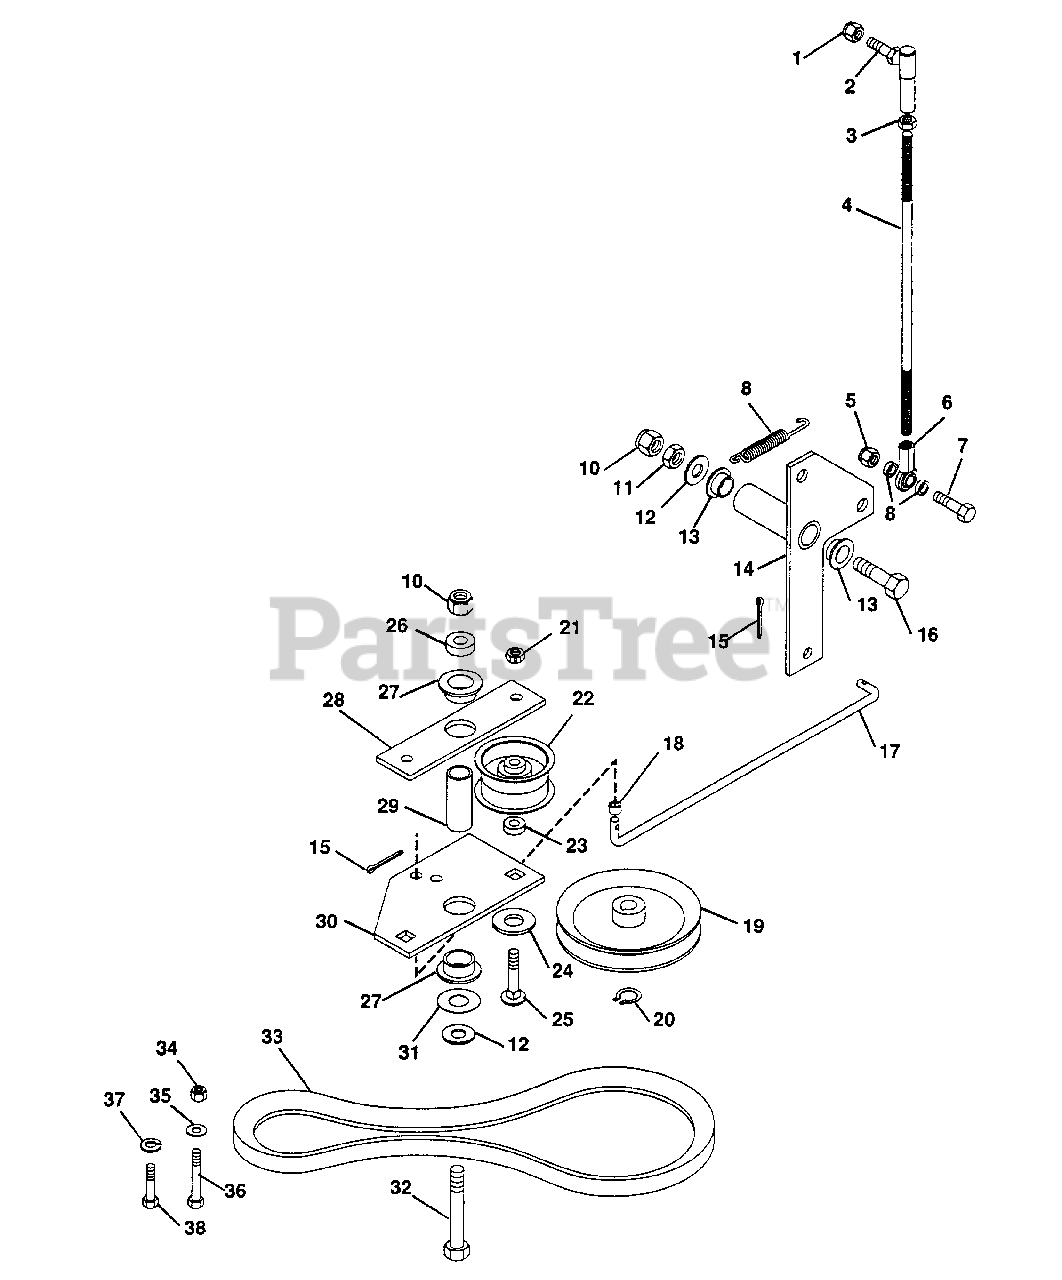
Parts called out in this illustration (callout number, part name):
1	NUT, LOCK 3/8-24
2	BALL JOINT, STEERING
3	NUT, HEX 3/8-24
4	ROD, CLUTCH ACTUATING
5	NUT, LOCK 3/8-16
6	ROD END, SPHERICAL BEARING
7	BOLT, HEX 3/8-16X1.50
8	BUSHING, ST. .391X.500X.17 STL.
9	SPRING, EXTENSION
10	NUT, LOCK 1/2-13
11	NUT, HEX 1/2-13
12	WASHER, FLAT .531X1.250X.100
13	BUSHING, FLANGE NYLON
14	WELDMENT, CLUTCH ARM
15	PIN, COTTER .09X.75
16	BOLT, HEX 1/2-13X4.50
17	ROD, TRACTION CLUTCH
18	BUSHING, .375X.500X.437
19	SHEAVE, TRANSMISSION
20	RING, RETAINING
21	NUT, LOCK 3/8-16
22	SHEAVE, IDLER
23	SPACER, IDLER .406X.750X.188
24	WASHER, FLAT .531X1.063X.095
25	BOLT, 3/8-16X1.75 RD HD SQ NK
26	SPACER
27	BUSHING, FLANGE NYLON
28	PLATE, IDLER
29	BUSHING, ST. .560X.745X2.04 STL.
30	PLATE, IDLER
31	RACE, BEARING THRUST
32	BOLT, HEX 1/2-13X3.00
33	BELT, ENGINE-TRANSMISSION DRIVE
34	NUT, LOCK 5/16-18
35	WASHER, FLAT .344X.688X.065
36	BOLT, HEX 5/16-18X1.75
